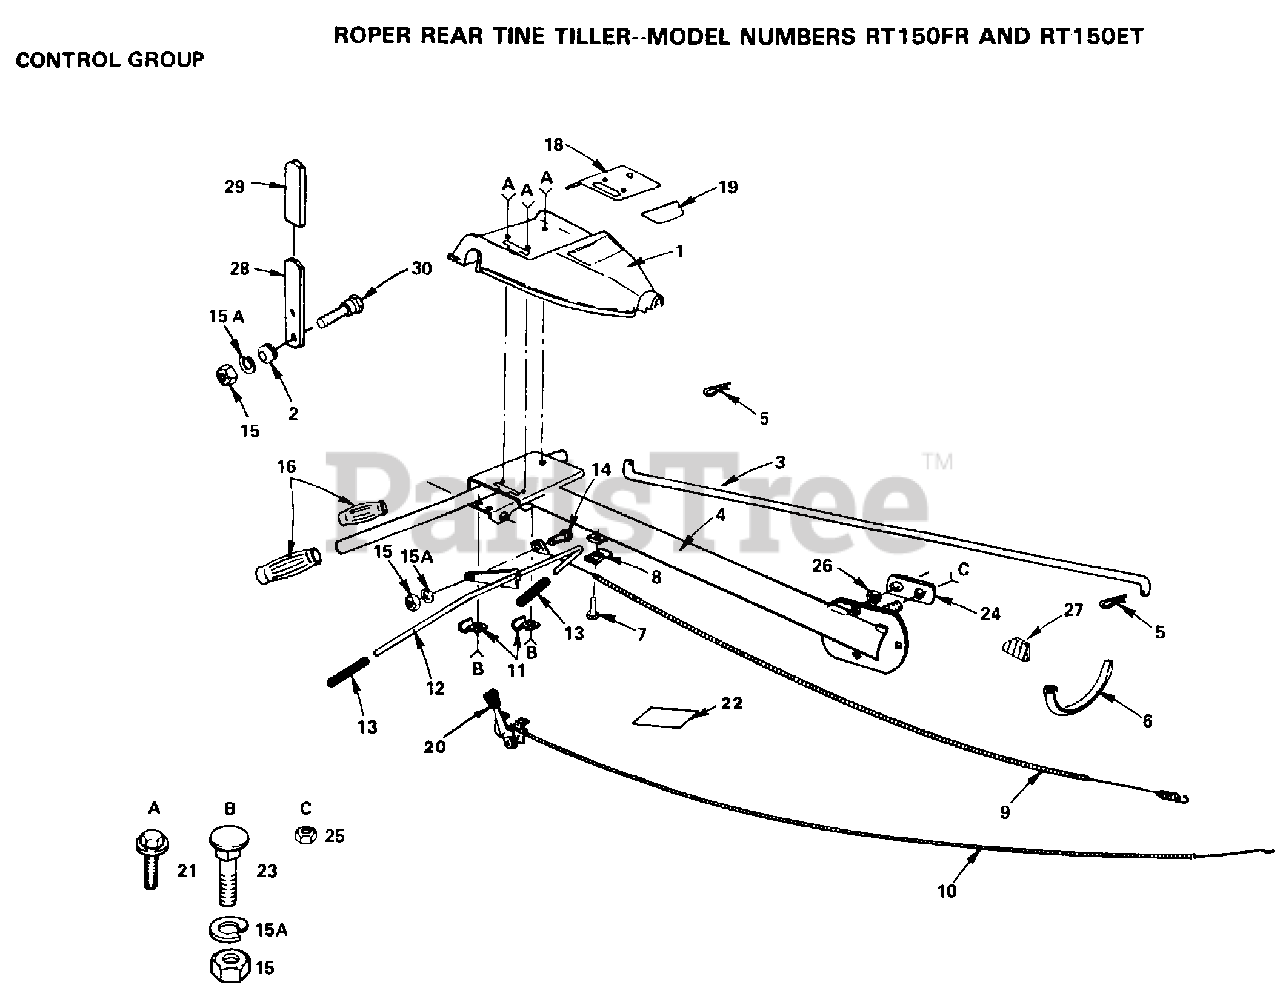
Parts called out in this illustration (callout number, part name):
1	PANEL - CONTROL
2	GROMMET CRT
3	SHIFT ROD CRT
5	RETAINER M
6	TIE CABLE CRT
8	CONDIUT CLIP T
9	CABLE.CLUTCH.CRT
10	CONTROL - THROTTLE
13	GRIP BAR CRT
14	SHOULDER BOLT ST
15A	LOCKWASHER
19	DECAL - CONTROL PANEL
20	KNOB CRT
21	SCREW
22	DECAL - HAND PLACEMENT
22	DECAL TI
23	BOLT
24	PLATE - LOCK
25	LOCKNUT
26	NUT FLANGE CRT
27	LOCK CRT
28	SHIFT HANDLE CRT
29	GRIP T
30	SHOULDER BOLT ST
